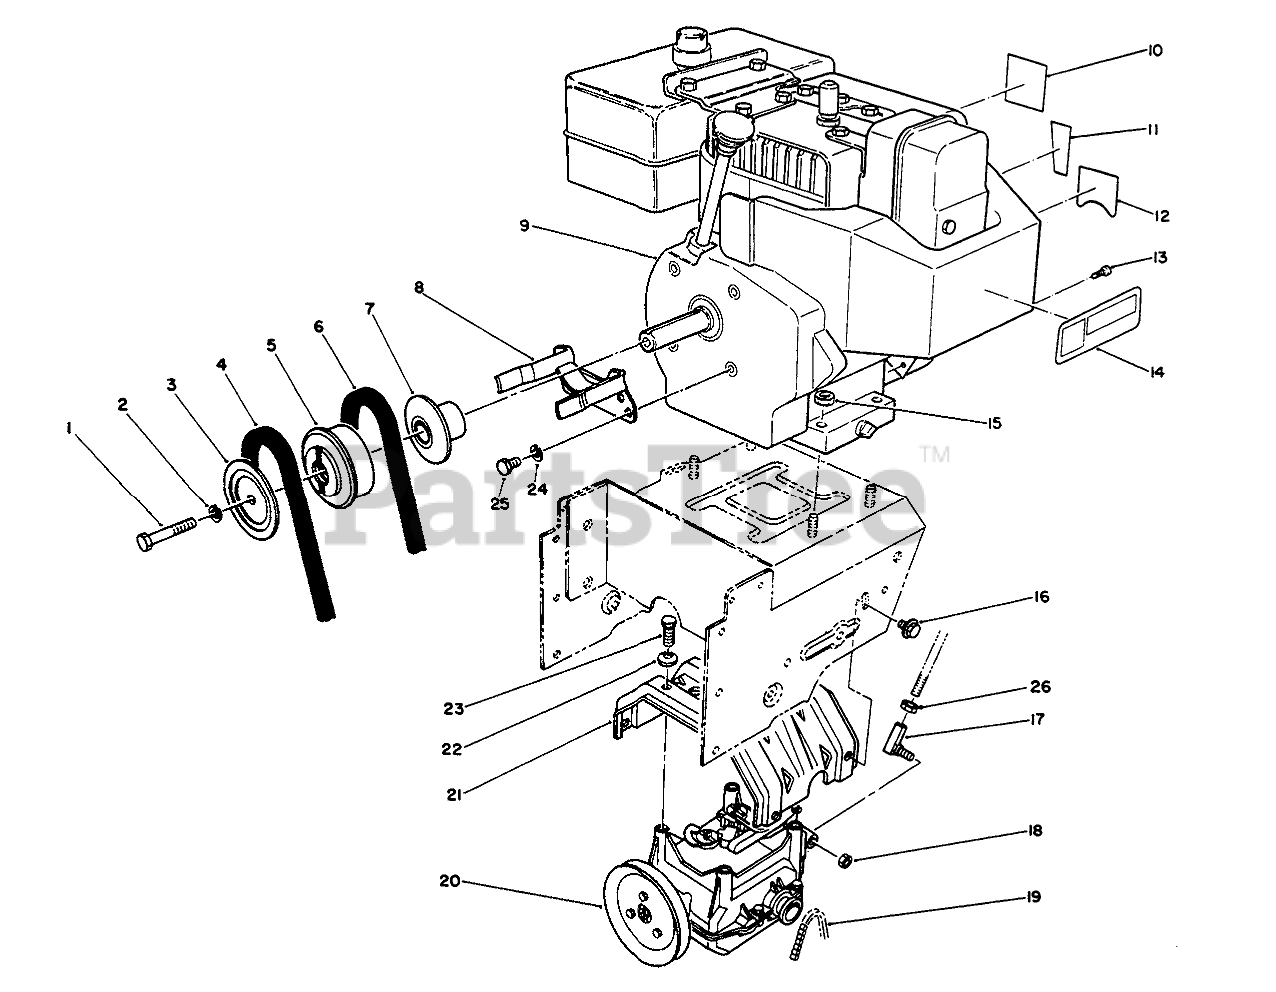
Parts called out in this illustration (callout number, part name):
1	SCREW-HH
2	WASHER-LOCK
3	SHEAVE-HALF, IMPELLER
4	V-BELT
5	PULLEY-ENGINE, CENTER
6	V-BELT-TRACTION
7	SHEAVE-HALF, TRACTION
8	Guide-Belt
10	DECAL-PRIMER
11	DECAL-THROTTLE
12	DECAL-CHOKE
13	SCREW-HWH
14	DECAL-HOT SURFACE, WARNING
15	NUT-HF
16	SCREW-HHF
17	JOINT-BALL
18	NUT-LOCK, NI
19	CHAIN
20	TRACTION GEARCASE ASM
21	Frame-Transmission
22	WASHER-SPRING
23	SCREW-HWHTF
24	WASHER-LOCK
25	SCREW-HH
26	NUT-HJ
